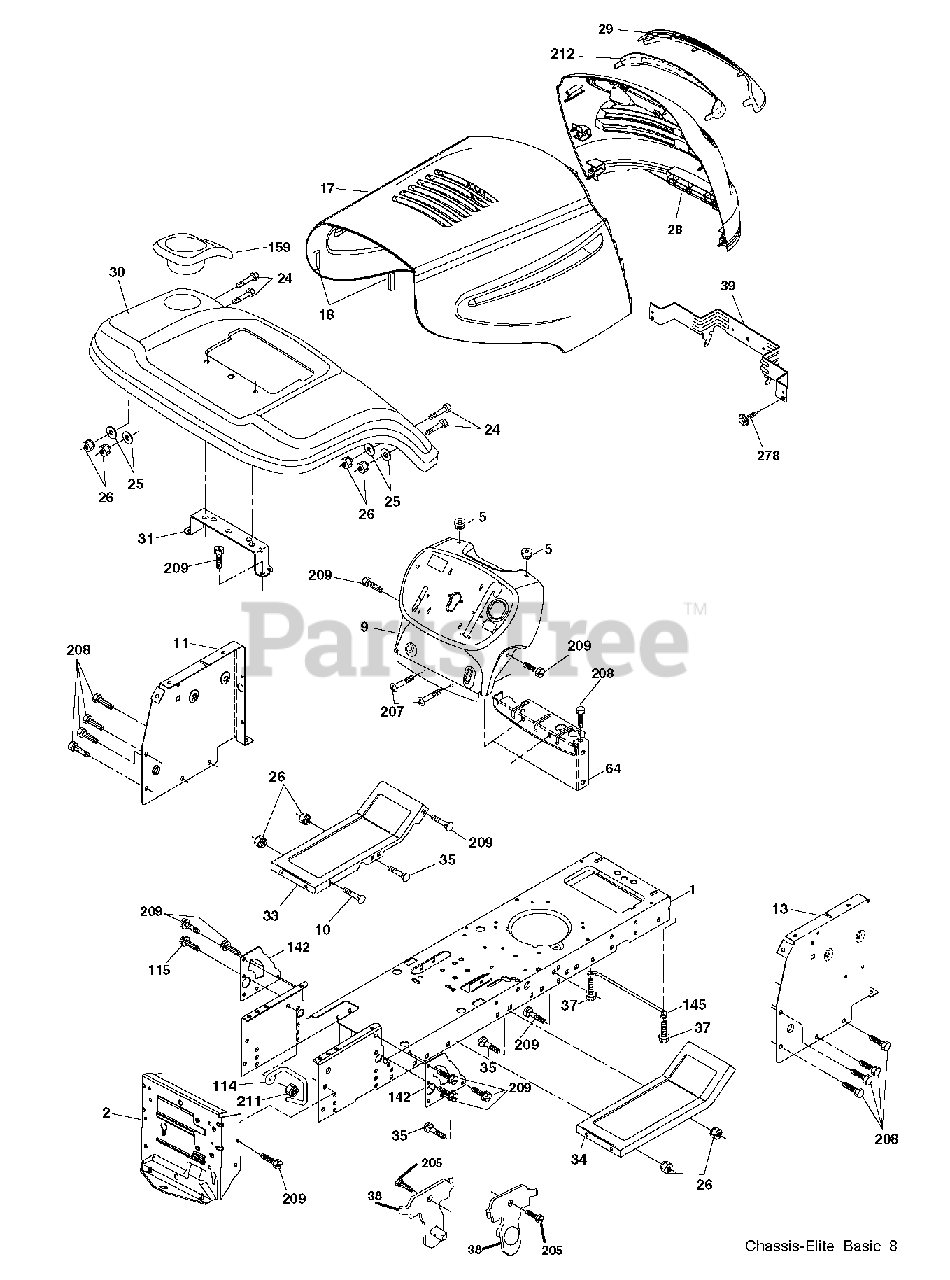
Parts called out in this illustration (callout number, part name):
1	CHASSIS STAMPING
2	DRAWBAR, 12GA
5	BUMPER.RUBBER.HOOD
11	PANEL.DASH.LH.LTX
17	HOOD.STEEL.ELITE.YELLOW
18	BUMPER.HOOD.LARGE.1.75"
25	WASHER
26	NUT
28	GRILLE.ASM.ALPHA
29	LENS.ALPHA.BAR.LT
30	FENDER.LTST.W/SHFT.CUP.YELLOW
31	BRACKET FENDER
33	FOOTREST.LH.YELLOW
34	FOOTREST.RH.YELLOW
37	SCREW LT
38	BRACKET.ASM.PIVOT.MOWER.REAR
39	BRACKET PIVOT
64	DASH LOWER
115	SCREW.3/8-16
142	PLATE REINFORCEMENT
145	ROD.PIVOT.HOOD
159	CUPHOLDER.BLACK
205	SCREW LT
207	SCREW, 5/16-18 X 1/2
208	SCREW 3/8-16X1/2
209	SCREW, 3/8-16X3/4
211	NUT LOCK FLG 3/8-16 UNC
212	INSERT.ALPHA.REFLECTIVE.LT.
278	SCREW.#10 X 0.750.BOS (2 2)
